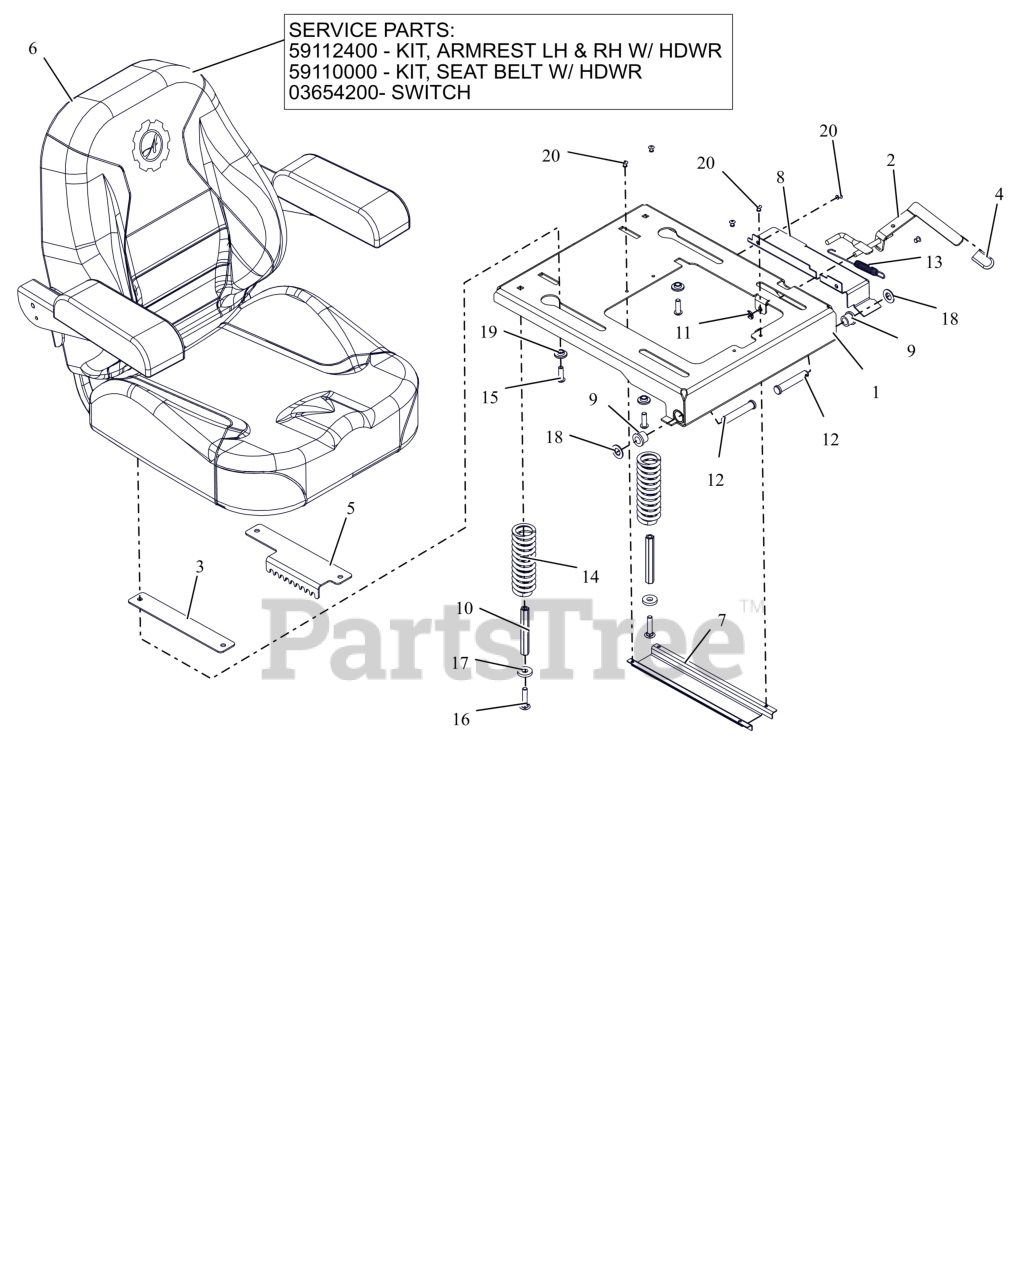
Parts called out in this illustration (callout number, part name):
1	WLDMT, SEAT PLATE HD
2	WLDMT, SEAT SLIDE LEVER
3	PLATE, ADJUSTABLE SEAT SLIDE
4	GRIP, SEAT LEVER, GREY
5	PLATE, HD SEAT ADJUSTMENT
6	SEAT, APEX
6	KIT-LH & RH ARM REST-05124700
6	KIT-SEAT BELT REPLACE-05007300
6	SWITCH- SEAT
7	GUARD,SEAT SWITCH
8	GUARD, SEAT PLATE CE
9	BSHG, FLG .516X.750X.625X.937
10	NUT, COUPLING 5/16X18 X 3.75
11	NUT-PUSH .312
12	PIN-CLIC .50X2.70X2.31 -ZCC
13	SG-TENS .06X.482X5.35
14	SPRING, COMPRESSION SEAT 224LB
15	BLT,SHCS-BTN .31-18X1.00 ZCC
16	BLT,RHSN .31-18X1.50 G5 ZCC
17	WSHR, FLT .406X1.00X.188 ZCC
18	WSHR, FLT .531X1.00X.063 ZCC
19	BSHG-FLG .325X.499X.3X.875
20	RIVET, .1875 AL/AL .126-.250
